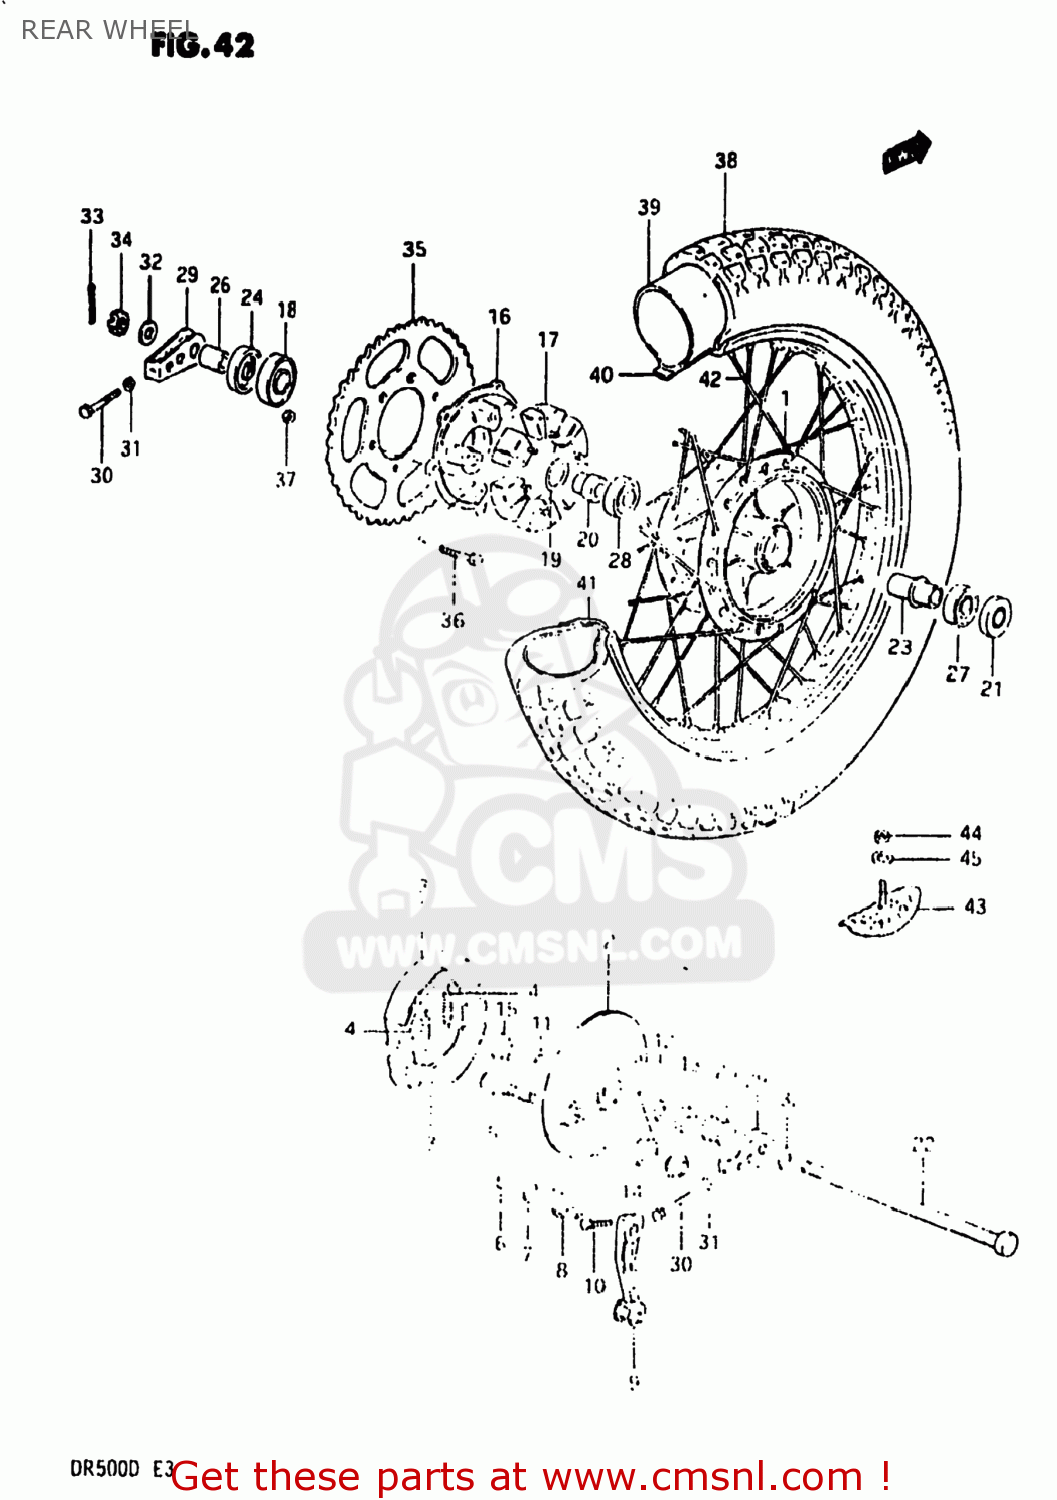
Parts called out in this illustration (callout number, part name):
1	DRUM,REAR HUB
2	PANEL,REAR HUB
3	SHOE,BRAKE (MCA)
4	SPRING
5	CAM,FRONT BRAKE
6	O-RING,BOSS
7	WASHER (15X24X1.6)
8	SPRING
9	LEVER,REAR BRAKE CAM
10	BOLT
11	BEARING(24X31X28)
12	WASHER
13	CVR,RR BRAKE AHR PNL DUST SEAL
14	SPHERICAL BRNG,TORQUE LINK
15	SPACER,REAR HUB PANEL
16	DRUM,REAR SPROCKET MOUNT
17	ABSORBER,RR HUB SHOCK
18	BEARING
19	O-RING
20	SPACER,REAR SPROCKET DRUM
21	OIL SEAL
22	AXLE,REAR
23	SPACER,REAR HUB BEARING
24	SEAL,OIL(30.5X52X8)
25	SPACER,REAR AXLE,RIGHT
26	SPACER (17X30.5X12.9)
27	BEARING
28	BEARING
29	ADJUSTER,CHAIN
30	BOLT
31	NUT
32	WASHER (17X30X3.2)
33	PIN,COTTER
34	NUT
35	SPROCKET,REAR (NT:47)(AL)
36	BOLT
37	NUT
38	TIRE
39	TUBE,INNER
40	PROTECTOR,WHEEL,INNER
41	RIM,REAR WHEEL
42	SPOKE ASSY,RR WHEEL
43	STOPPER,BEAD
44	NUT
45	WASHER
